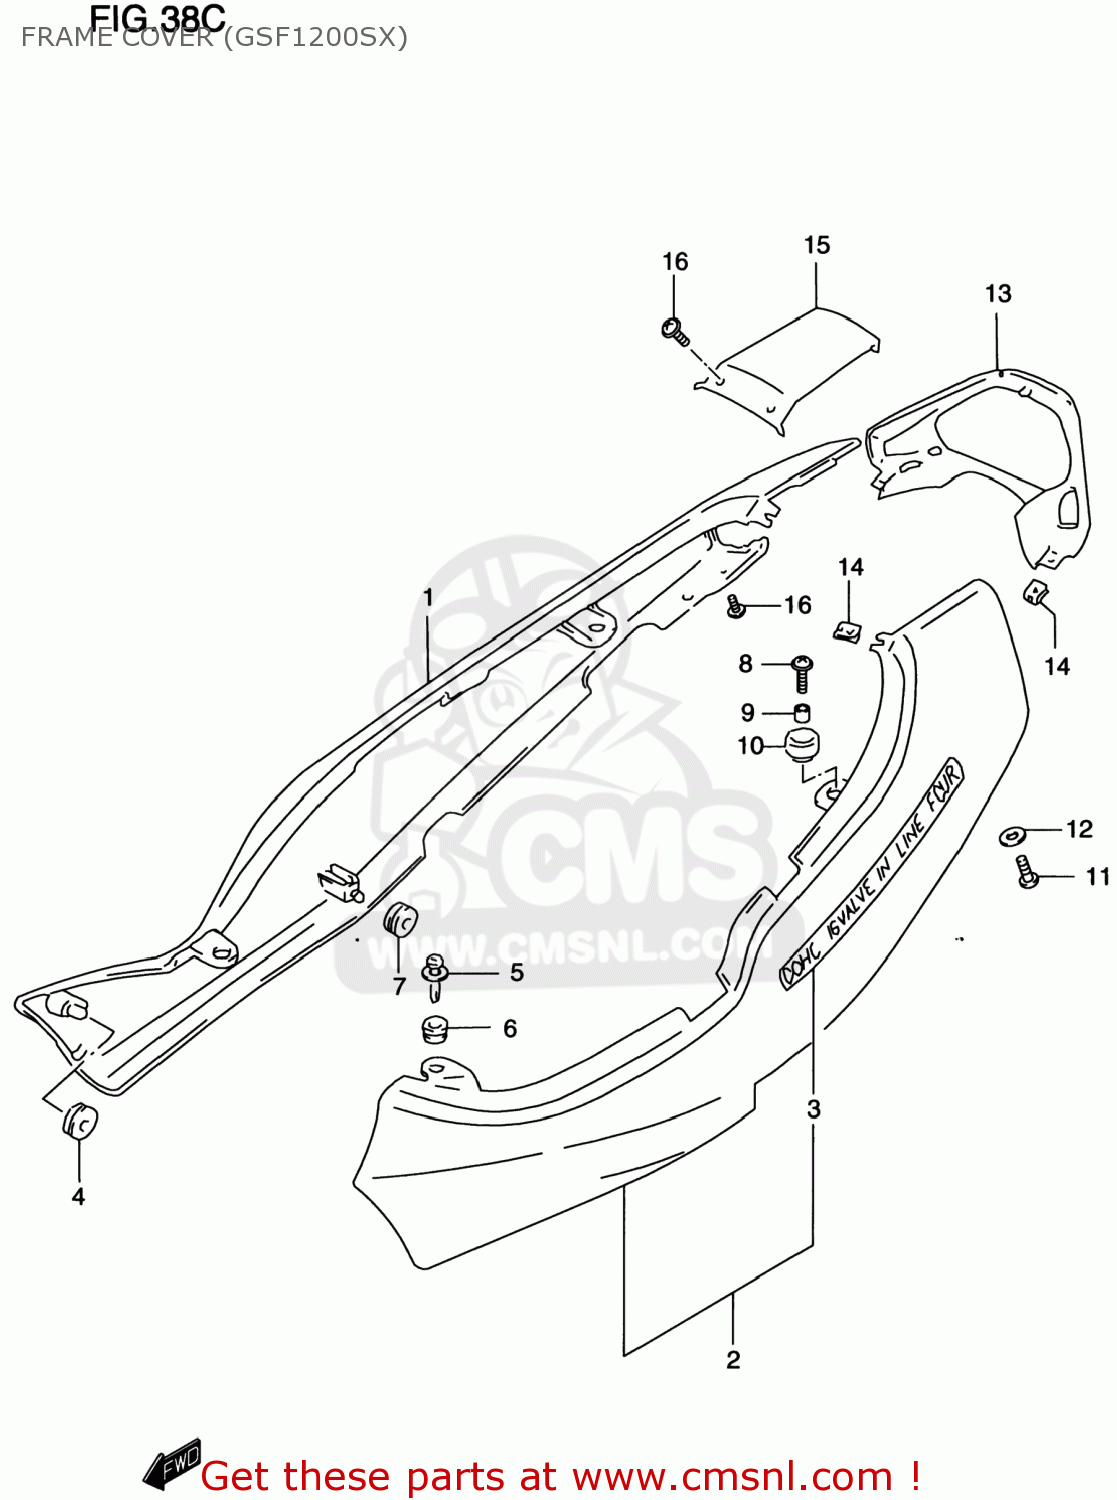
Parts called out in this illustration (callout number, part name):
1	COVER,FRAME,R(BLACK)
2	COVER,FRAME,L(BLACK)
3	EMBLEM,FRAME COVER
4	CUSHION,FRAME COVER FR
5	CLIP
6	CUSHION
7	CUSHION
8	SCREW(6X20)
9	SPACER(6.5X10X9.4)
10	CUSHION
11	SCREW
12	WASHER(6.3X16X1.5)
13	COVER,FRAME RR
14	NUT
15	COVER,FRAME CTR
16	SCREW
